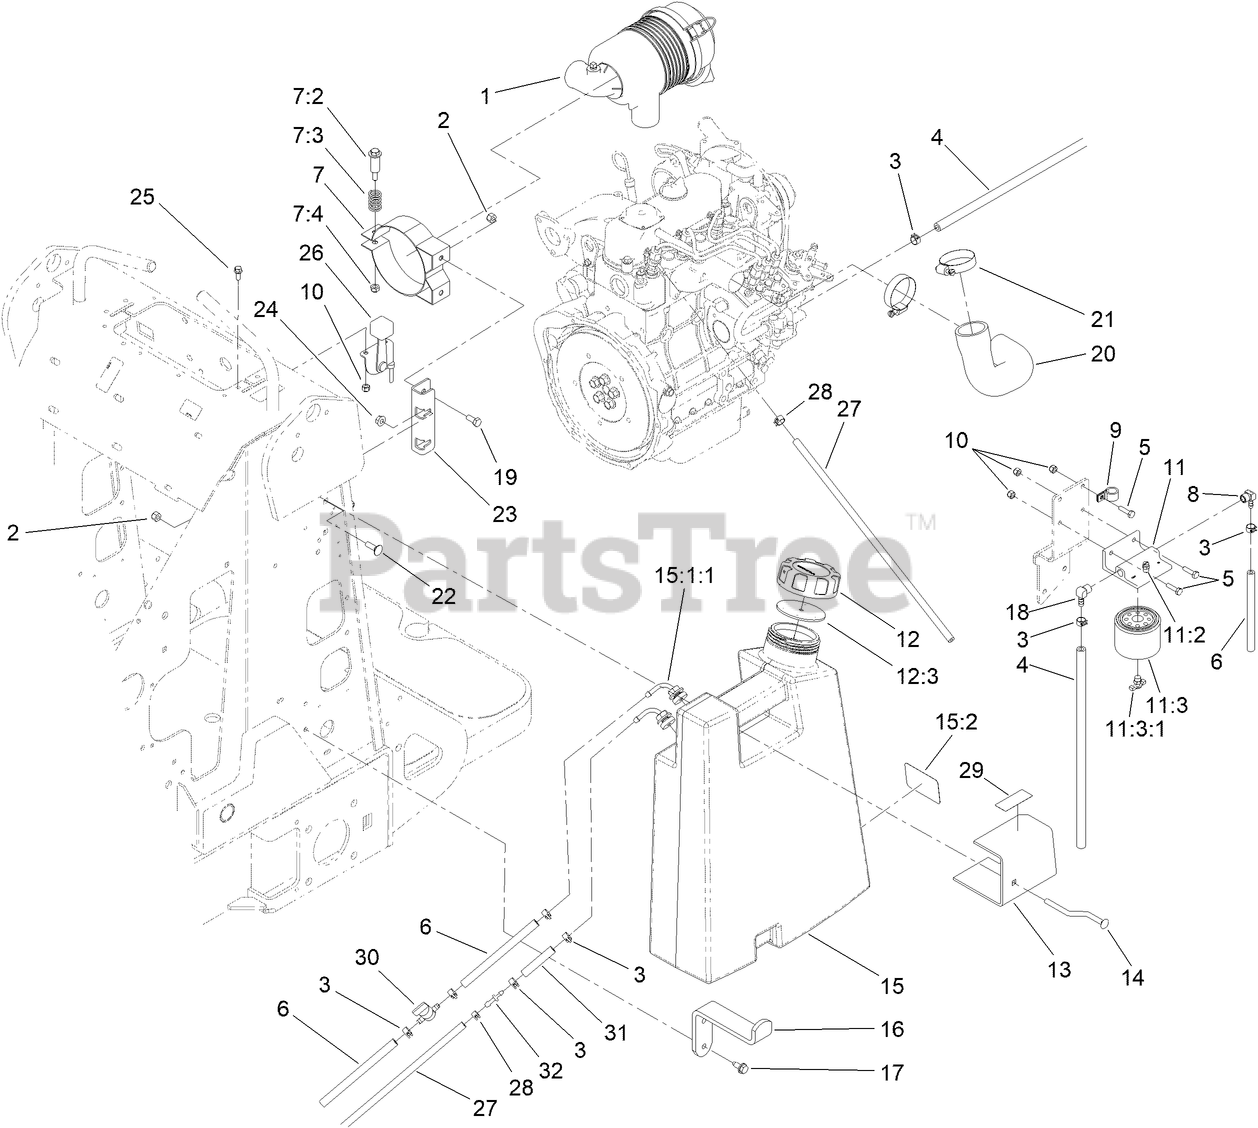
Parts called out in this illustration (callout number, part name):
1	AIR CLEANER ASM
2	NUT-LOCK, NI
3	CLAMP-HOSE
4	HOSE-FUEL
5	SCREW-HH
6	HOSE-FUEL
7	AIR CLEANER MOUNTING BAND ASM
7:3	SPRING
7:4	NUT-LOCK, NI
8	ELBOW
9	CLAMP-CABLE
10	NUT-LOCK, NI
11	FILTER HEAD ASM
11:2	VENT-AIR
11:3	ELEMENT-SPIN ON
11:3:1	VALVE-DRAIN
12	CAP-FUEL, DIESEL
12:3	GASKET-VENTED
13	PLATE-MOUNT, LEFT
14	BOLT-MOUNT
15	TANK-FUEL, LH
15:1:1	FITTING-FUEL, BULKHEAD
15:2	REFLECTOR
16	MOUNT-BOTTOM, TANK
17	SCREW-HWHTF
18	FITTING-HYD, 90
19	SCREW-HH
20	HOSE-CLEANER, AIR
21	CLAMP-HOSE
22	BOLT-CARR
23	MOUNT-CLEANER, AIR
24	NUT-HF
25	SCREW-HHF
26	CONTROL-THROTTLE
27	HOSE-FUEL
28	CLAMP-HOSE
29	DECAL-LOW SULFUR
30	VALVE-FUEL
31	HOSE-FUEL
32	FITTING-STRAIGHT
